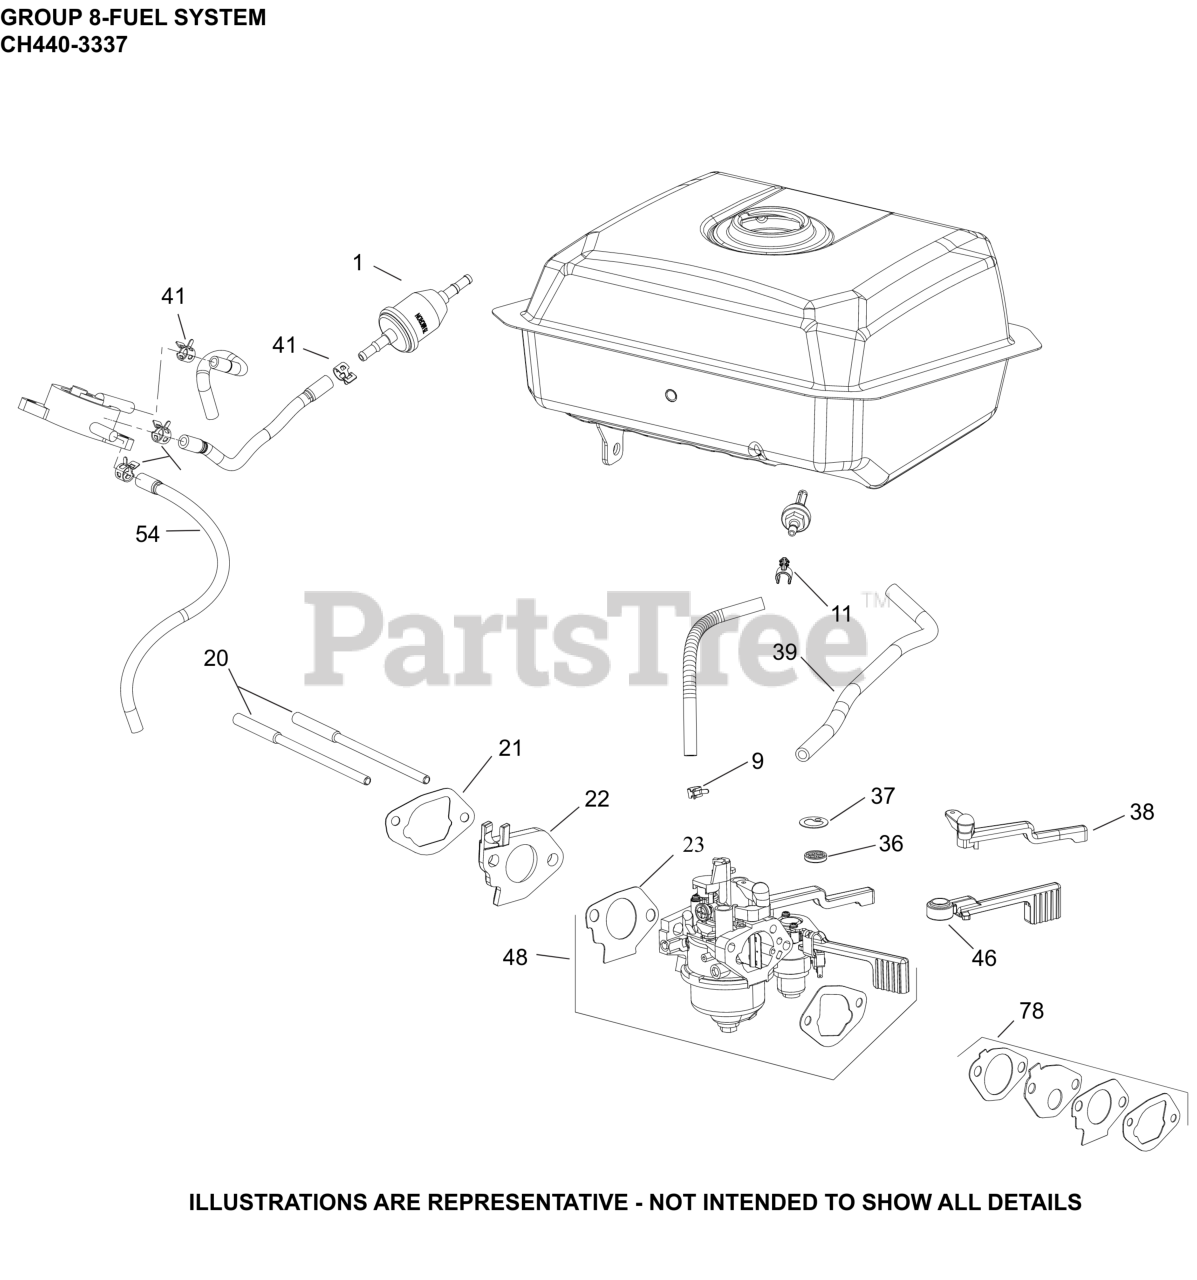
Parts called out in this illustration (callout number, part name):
1	FILTER,FUEL 75 MICRON (GRAVTY FEED)
9	CLAMP, FUEL LINE
11	CLIP, FUEL HOSE
20	STUD, CARBURETOR
21	KIT, GASKET INTAKE
22	KIT, INSULATOR
23	GASKET, CARB TO INSULATOR
36	SEAL, INLET VALVE
37	KIT, FUEL SCREEN
38	LEVER, CHOKE
39	HOSE, FUEL LOW-PERMEATION (CKY)
41	CLAMP, HOSE
46	KIT, FUEL SHUTOFF LEVER
48	KIT, CARBURETOR COMPLETE
54	FUEL HOSE, LOW PERMEATION
78	KIT, RESTRICTOR PLATE
NI	KIT, HIGH ALT (4000-8000 FT)
NI	KIT, HIGH ALT (8,000+ FT)
NI	KIT, CARBURETOR REPAIR
